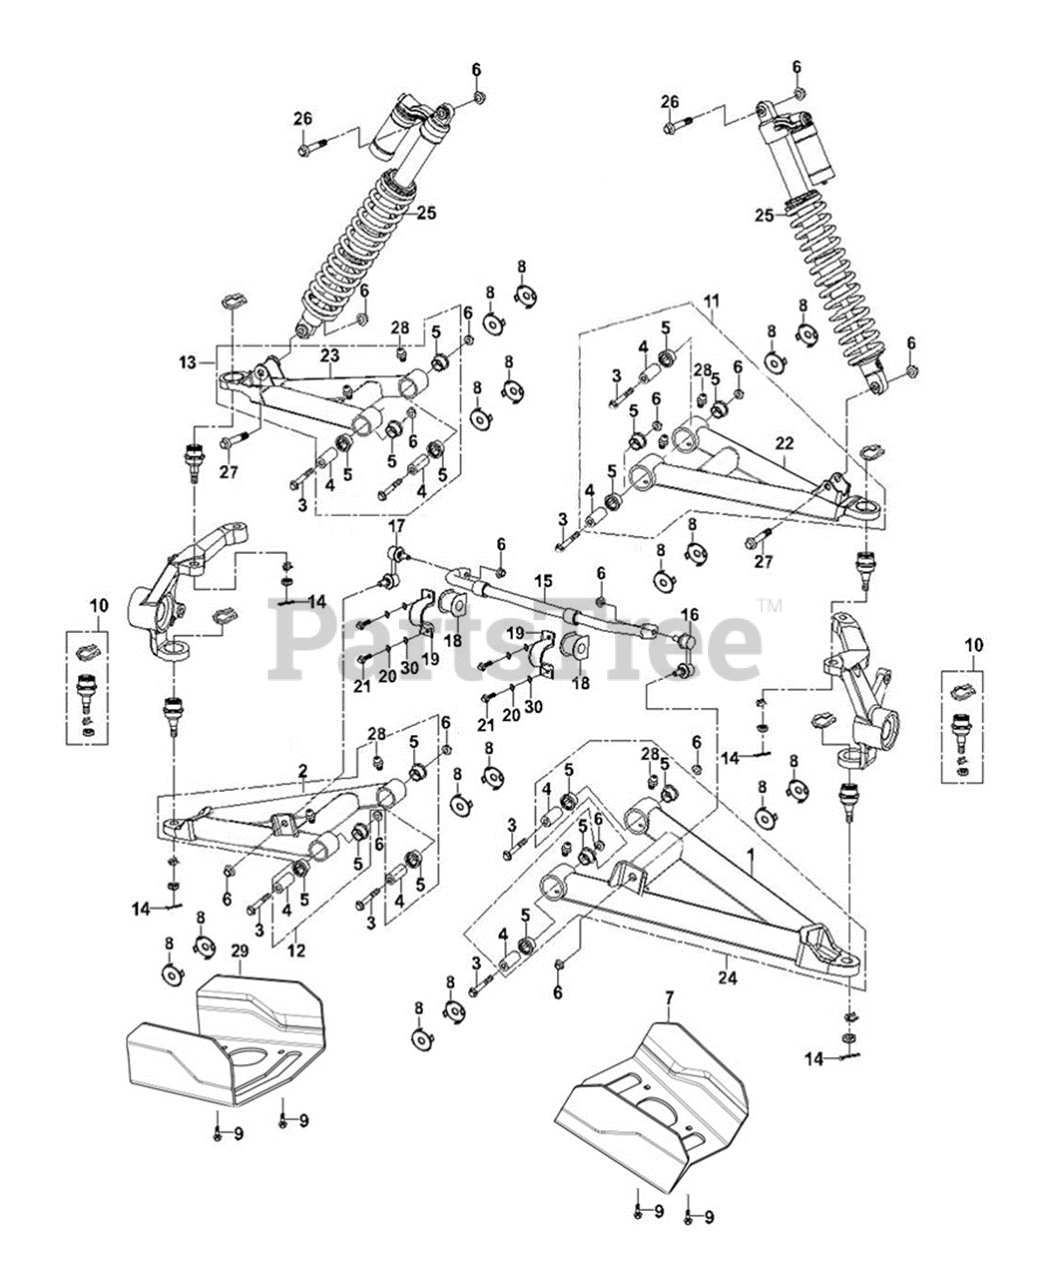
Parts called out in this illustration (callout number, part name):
1	Arm Welding Kit(Front Left Lower)
2	Arm Welding Kit(Front Right Lower)
3	HEX HEAD FLANGE BOLT M10X1.25-80
4	BUSHING 10.3X23X49.4
5	SHOULDER SPACER
6	LOCK NUT M10X1.25
7	SHIELD CV BASIC
7	SHIELD CV - BASIC I
8	BUSHING CAP I
9	SCREW M6X16
10	BALL JOINT ASSEMBLY
11	UPPER A-ARM ASSEMBLY (FRONT LH)
12	LOWER ARM ASSEMBLY (FRONT RH)
13	UPPER A-ARM ASSEMBLY (FRONT RH)
14	COTTER PIN 2.5X30
15	STABILIZER BAR (FRONT)
16	ROD BALL KIT - RIGHT
17	ROD BALL KIT - LEFT
18	BUSHING - RUBBER U-TYPE
19	PRESS BLOCK REAR ANTI-ROLL BAR
20	SPRING WASHER
21	HEX FLANGE BOLT M10X1.25X20
22	Arm Welding Kit(Front Left Upper )
23	Arm Welding Kit(Front Right Upper)
24	LOWER ARM ASSEMBLY (FRONT LH)
25	FRONT SHOCK ABSORBER
26	HEX FLANGE BOLT M10X1.25X55
27	HEX FLANGE BOLT M10X1.25X60
28	SWING ARM NOZZLE
29	SHIELD CV III
29	CV SHIELD - BASIC II
